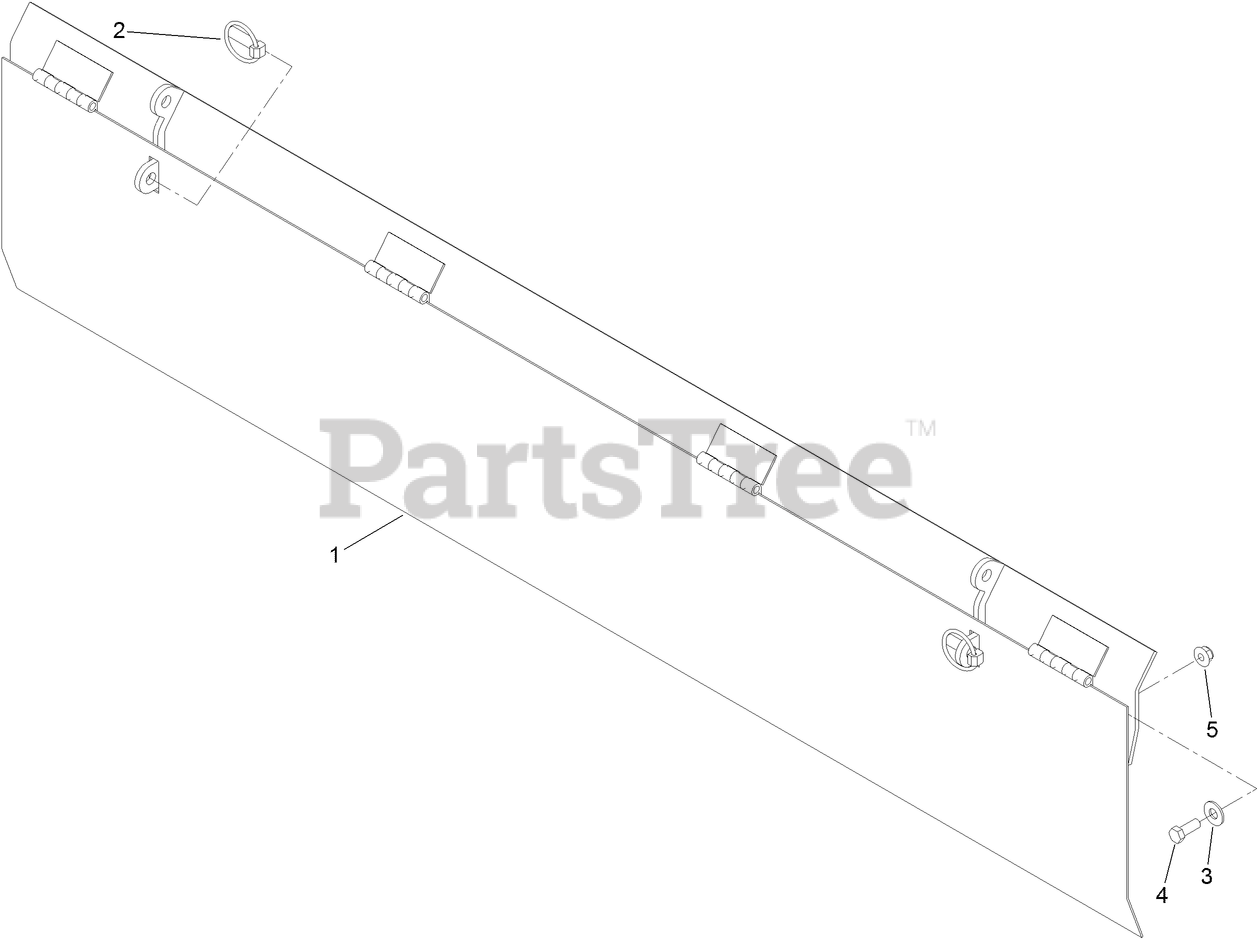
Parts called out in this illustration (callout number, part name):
1	DEFLECTOR-BROOM
2	PIN-LYNCH
3	WASHER-FLAT
4	SCREW-HH
5	NUT-HF, NI
